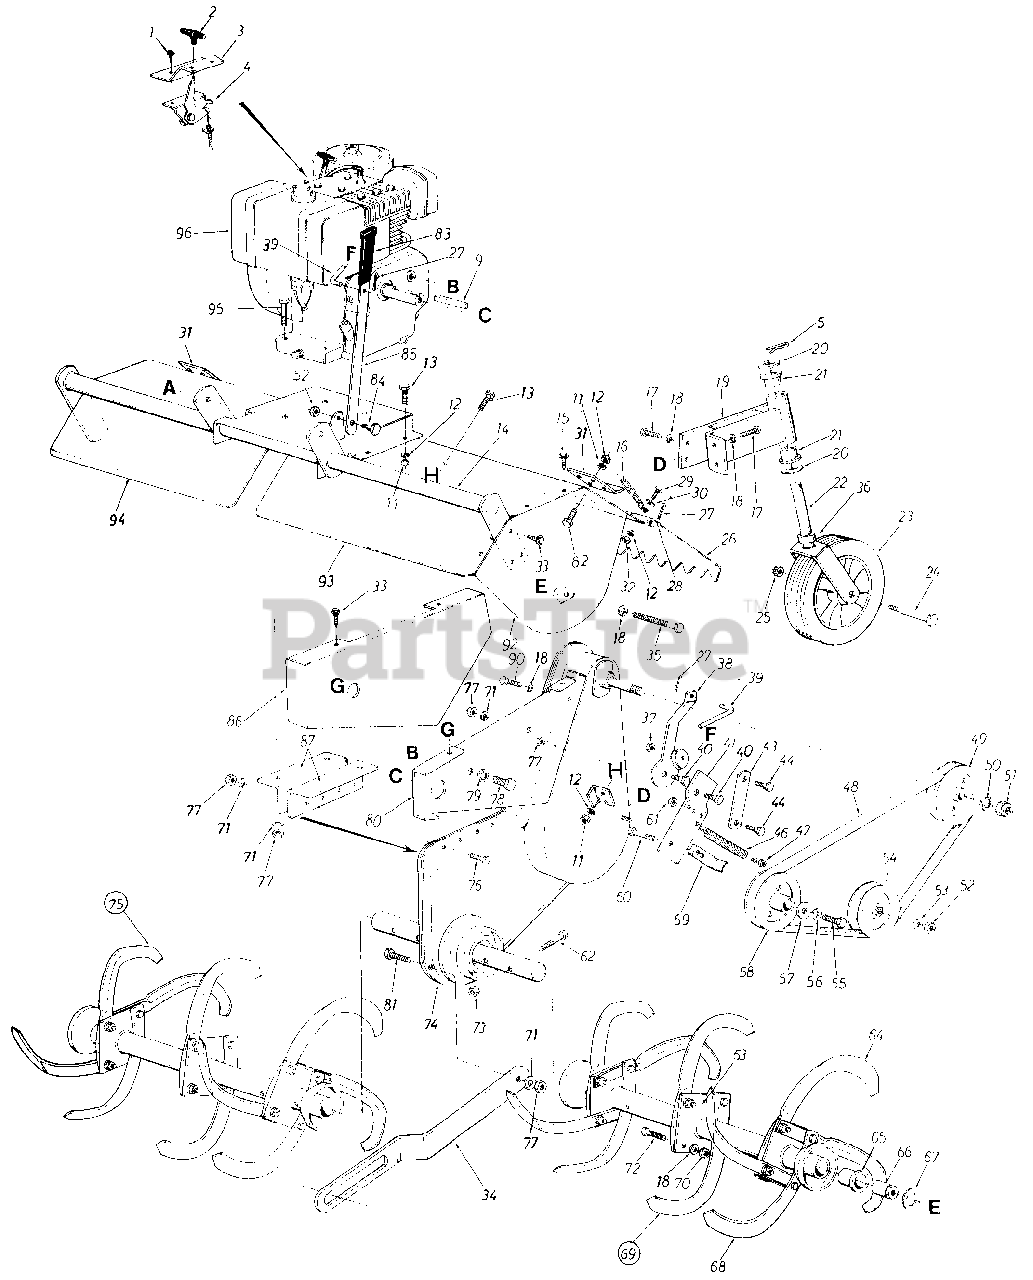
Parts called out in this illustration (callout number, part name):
1	Hex Wash. Hd. Self-Tap Scr. #8 x .50" Lg.
2	Throttle Control Knob
3	Throttle Control Bracket
4	Throttle Control Ass'y. Comp.
5	Internal Cotter Pin
11	Hex Nut 1/4-28 Thd.
12	L-Wash. 1/4" I.D.
13	Hex Bolt 1/4"-28 x .62" Lg.
16	#2 Dog Chain x 20" Lg.
17	Hex Bolt 3/8-24 x .75" Lg.
18	L-Wash. 3/8" I.D.
21	Flange Bearing 3/4" I.D. x 1.00" O.D.
22	Swivel Wheel Caster
23	Wheel Assembly 10.0 x 2.75
24	Shoulder Bolt .623" I.D. x 3.62" Lg.
25	Hex Cent. L-Nut 7/16-14 Thd.
28	L.H. Flap Rod
29	Hex Bolt 1/4-20 x .62" Lg.
30	Fl-Wash. 1/4" I.D.
33	Hex Wash. Hd. Self-Tap Scr. 1/4" x .62" Lg.
35	Hex Bolt 3/8-16 x 1.25" Lg.
36	Spacer .752" I.D. x 1.25" O.D.
37	Hex Cent. E-Nut 5/16-18 Thd.
40	Shoulder Bolt 7/16" Dia. x 1.75" Lg.
46	Extension Spring .62" O.D. x 6.12" Lg.
47	Hex Crown Nut 3/8-24 Thd.
48	"V"-Belt 1/4" x 43" Lg. (Kevlar)
49	1/2" "V"-Pulley 4.75" O.D. x .625" Bore
50	L-Wash 5/8" I.D.
51	Hex Ins. L-Nut 5/8-18 Thd.
52	Hex Cent. L-Nut 3/8-16 Thd.
53	Fl-Wash. 3/8" I.D.
54	Idler Pulley 4.0" O.D.
56	L-Wash. 7/16" I.D.
57	Fl-Wash. 7/16" I.D. 1.38" O.D.
58	1/2" "V"-Pulley .475" O.D. x 1.00" Bore
61	Hex Cent. L Nut 5/16-18 Thd.
62	Hex Bolt 7/16-14 x 2.00" Lg.
65	Flange Bearing 1.00" I.D.
67	Thrust Wash. 1/2 I.D. 1.55" O.D.
69	Tine Assembly Comp - L.H.
70	Hex Nut 3/8-24 Thd.
71	L-Wash. 5/16" I.D.
72	Hex Bolt 3/8-24 x 1.50" Lg.
73	Hex Cent. L-Nut 7/16-14 Thd.
77	Hex Nut 5/16-18 Thd.
78	Hex Bolt 1/2-20 x .88" Lg.(Grade 5)
79	L-Wash. 1/2" I.D.
80	Clutch Support Bracket
82	Hex Bolt 1/4-28 x .75" Lg.
83	Plastic Grip
84	Shoulder Bolt .498 Dia. x .212 Lg.
85	Clutch Handle
90	Hex Bolt 3/8-16 x .62" Lg.
96	8 H.P. Engine
